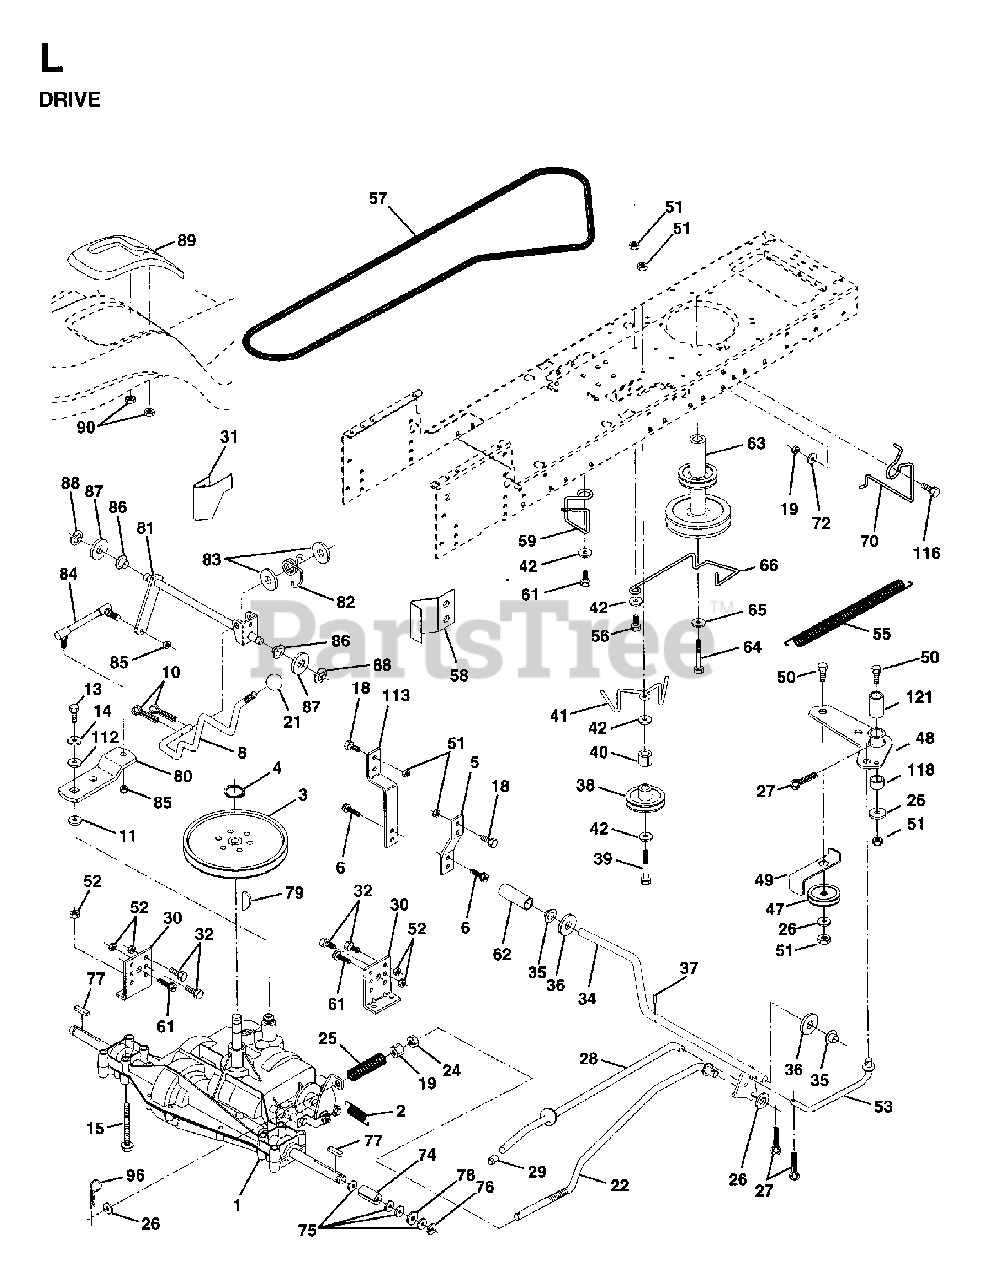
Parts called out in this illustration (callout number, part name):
2	SPRING,BRAKE RETURN
3	PULLEY TRANS
4	RETAINING RING LT
5	STRAP TORQUE
6	SCREW
8	ROD SHIFT FENDER
10	PIN COTTER
11	WASH-SHFT PLT LT
13	BOLT 1/4-28X3/4
14	LOCKWASHER
15	BOLT HEX 5/16-18 GR 5
19	NUT
21	KNOB.DELUXE.(PISTOL.GRIP).BLAC
22	ROD BRAKE
24	NUT
25	SPRING ROD LT
27	COTTER PIN
28	ROD BRAKE PARK LT
29	PLUNGER CAP
30	BRACKET TRANSAXLE
31	KEEPER BELT LH
32	BOLT
34	SHAFT, FOOT PEDAL
35	BEARING.NYLON
36	WASHER LT
37	DRIVE PIN
38	PULLEY.IDLER.FLAT
41	KEEPER, BELT IDLER
42	WASHER
47	IDLER PULLEY
48	BELLCRANK ASSEMBLY
49	RETAIN BELT
50	BOLT
51	LOCKNUT
52	LOCKNUT
53	LINK, CLUTCH LT
55	SPRING, RETURN LT
59	KEEPER CENTER SPAN
61	SCREW
62	PEDAL COVER T
63	PULLEY ENGINE
64	BOLT
65	LOCKWASHER
66	KEEPER BELT ENGINE
70	KEEPER BELT ENG
74	SPACER AXLE
76	E-RING LT
77	SQUARE KEY
80	ARM SHIFT
81	SHAFT ASM CROSS 20"T
82	SPRING,TORSION
83	WASHER
84	ROD,TIE
85	NUT LOCK CENTER 1/4 -28 FNTHD
86	BUSHING.STEERING.ROD
88	KLIP RING
89	CONSOLE SHIFT
96	RETAINER M
112	WASHER LT
113	STRAP TORQUE LH LT
116	BOLT
118	SPACER BELLCRANK
121	NYLINER CLUTCHING
